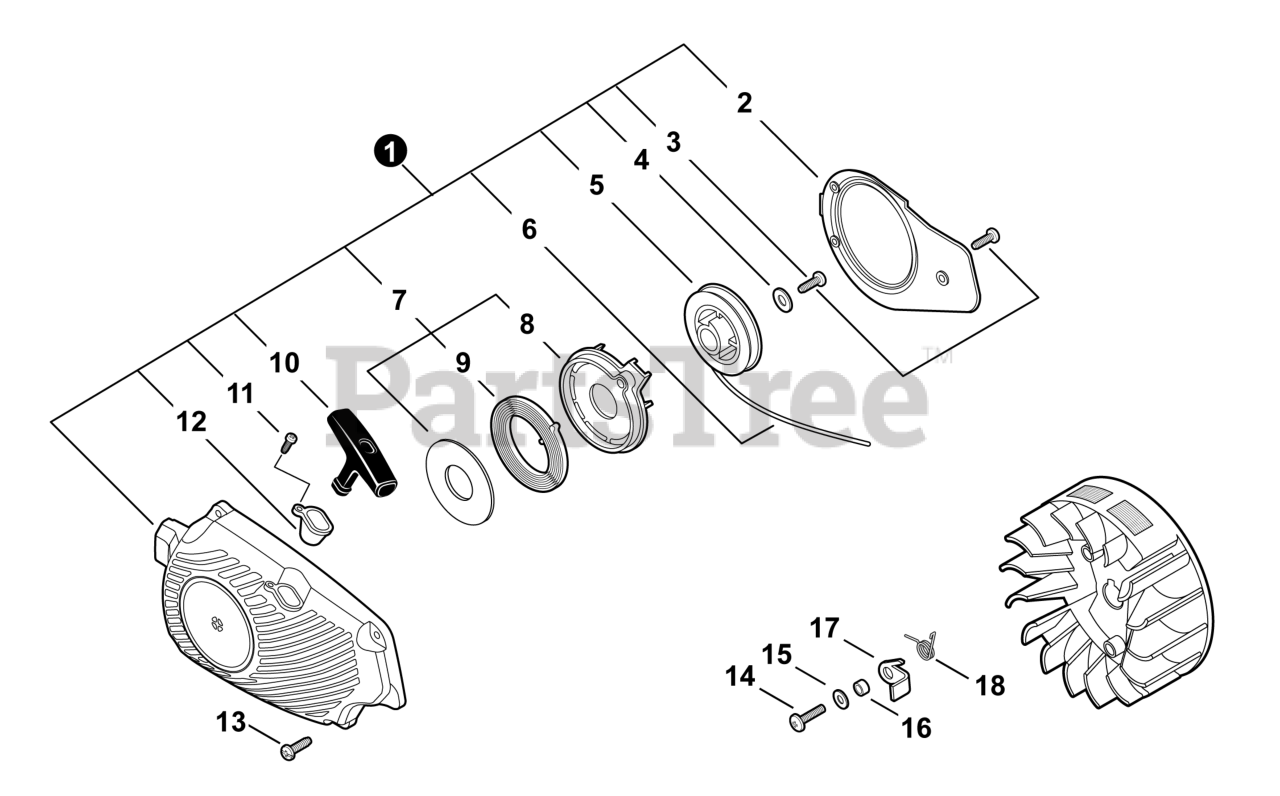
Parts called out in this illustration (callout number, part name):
1	STARTER ASSY
2	PLATE, GUIDE
3	SCREW 4x14
4	WASHER 4.1x15.5x1T
5	REEL, ROPE
6	ROPE, STARTER 3.0x850
7	SPRING KIT, RECOIL
8	PLATE, STARTER
9	SPRING, RECOIL
10	GRIP, STARTER
11	SCREW 3x14
12	GUIDE, ROPE
13	SCREW 4x16
14	SCREW 5x12
15	WASHER 5.5x12x0.8
16	SPACER 5.2x8x2.1
18	SPRING, TORSION
